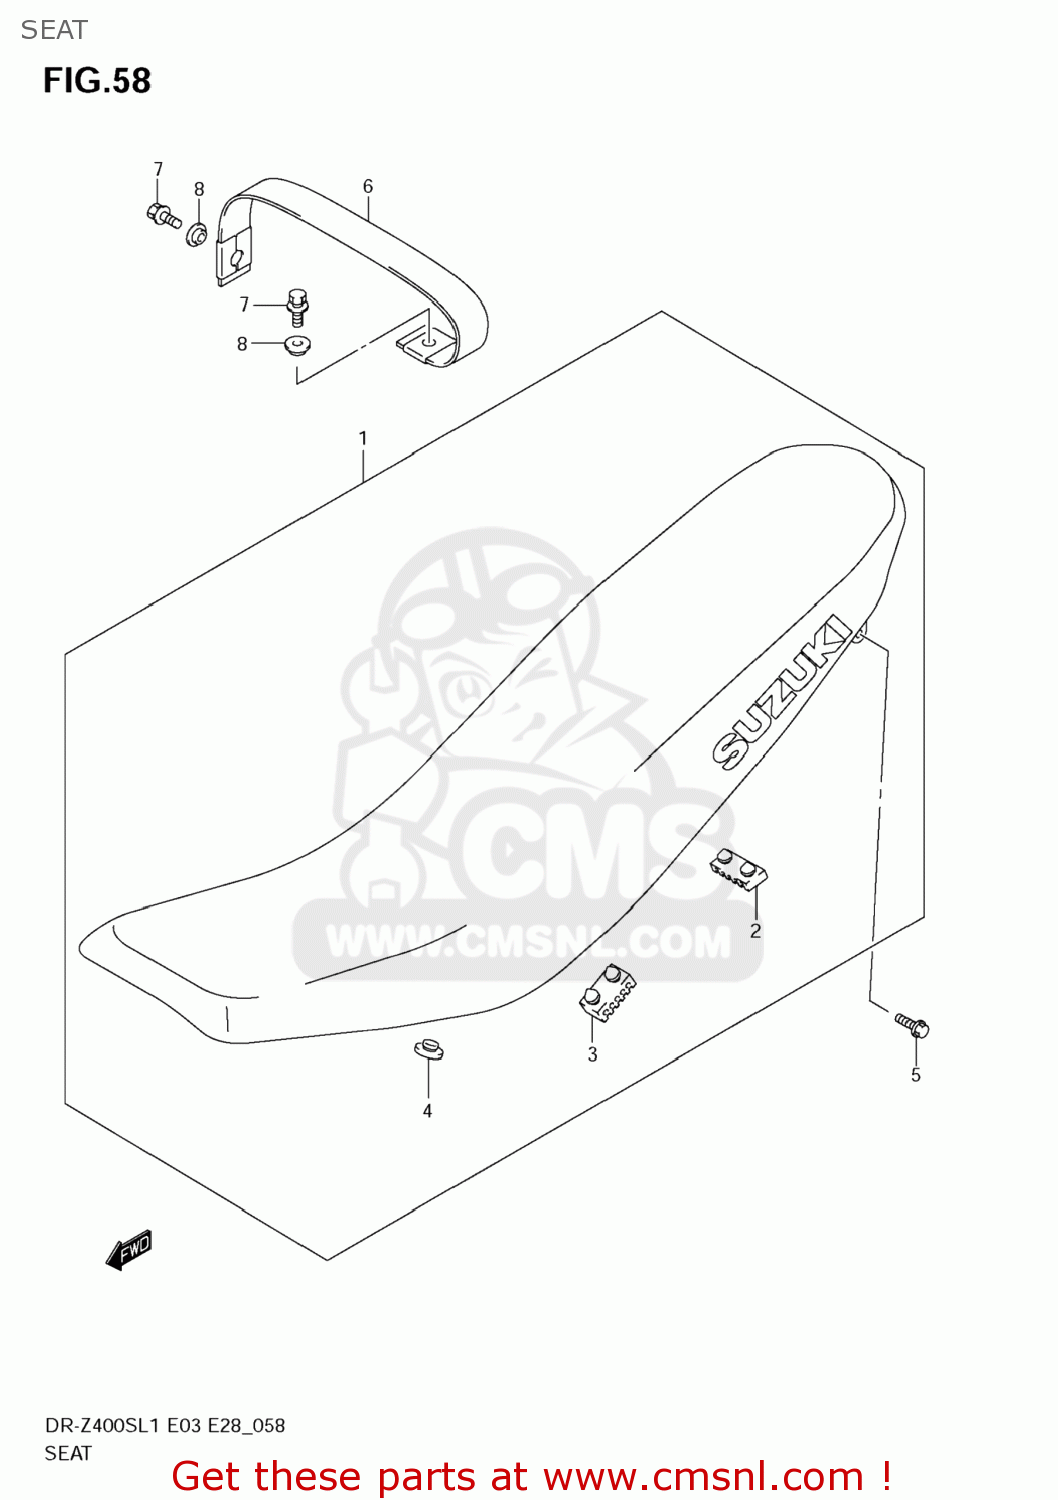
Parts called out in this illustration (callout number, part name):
1	SEAT ASSY,HIGH,SILVER
2	CUSHION,SEAT(40X20X6)
3	CUSHION,SEAT(40X20X15)
4	CUSHION
5	BOLT(6X20)
6	BAND ASSY,SEAT(GRAY)
7	BOLT(6X25)
8	WASHER
